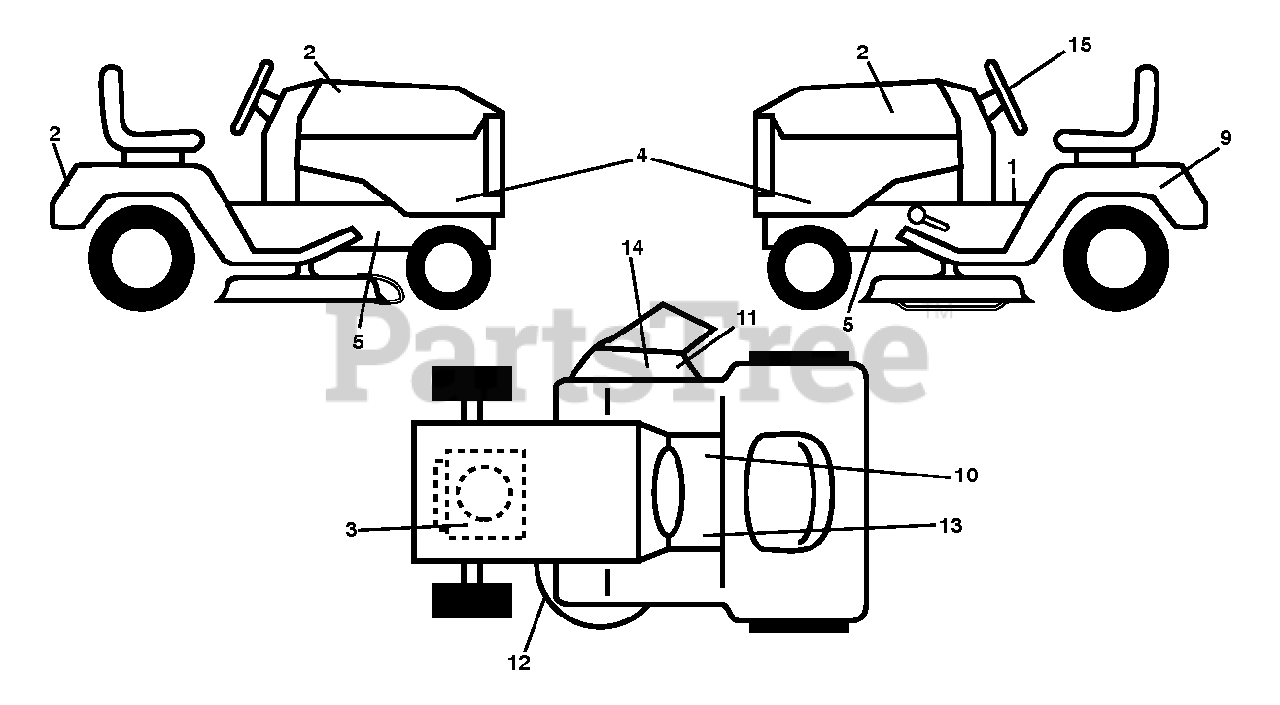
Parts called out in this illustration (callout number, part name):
1	DECAL.READ.OWN.MAN.SYMBOL.LT
2	DECAL, DIXON LOGO, DOMED
3	DECAL.ENGINE.WARNING
4	DECAL.LTPRED.SDPNL.17/38.DIXON
5	DECAL.CHASSIS.HOT.MUFFLER
9	DECAL BTRY SYMBOLS
10	DECAL.PARKING.BRAKE.SADDLE.LT
11	DECAL.DFLCTR.WARNNG.CTFNGR.SYM
12	DECAL.DECK.SCH.36,38,94.NONCR
13	DECAL.FNDR.SDLE.BRAKE.CLUTCH.6
15	DECAL.WHEEL.STEER.DIXON
